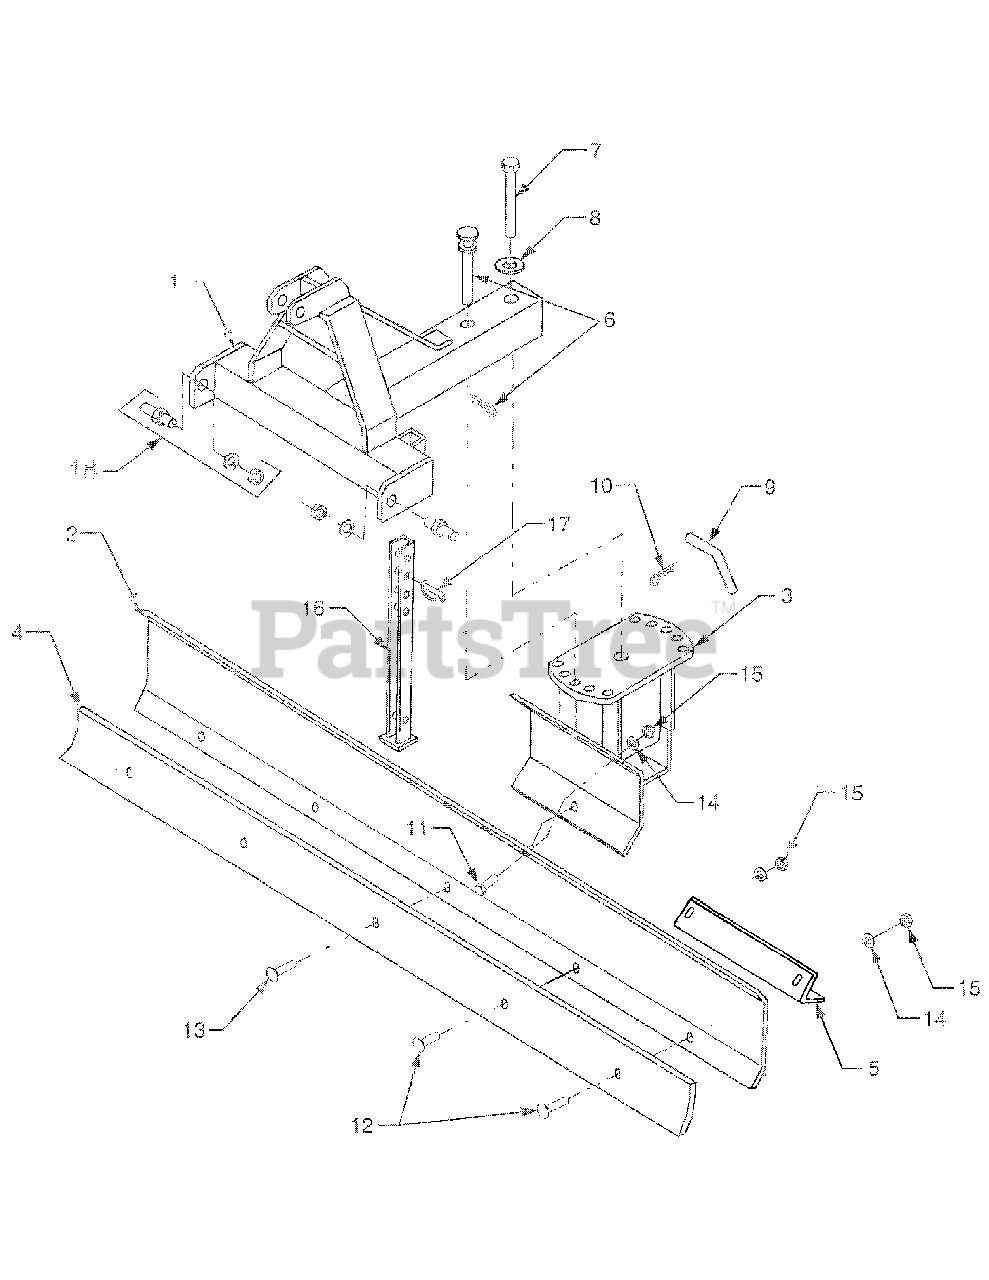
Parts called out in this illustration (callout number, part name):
2	MOLD BOARD 6'
3	SWIVEL
4	SCRAPER BLADE 6'
5	SKID SHOE (OPTIONAL)
6	SWIVEL PIN W/COTTER
7	1" X 6" HEX BOLT PLATED
8	1" ID FLAT WASHER
9	BENT PIN
10	COTTER PIN
11	5/8"-11 X 2" HEX BOLT PLATED
12	5/8"-11 X 1.5" PLOW BOLT
13	5/8" X 2" GR5 PLOW BOLT ZINC
14	5/8" LOCKWASHER
15	5/8" HEX NUT
16	FOOT STAND
17	LOCK PIN
18	7/8" HITCH PIN W/LW & NUT
